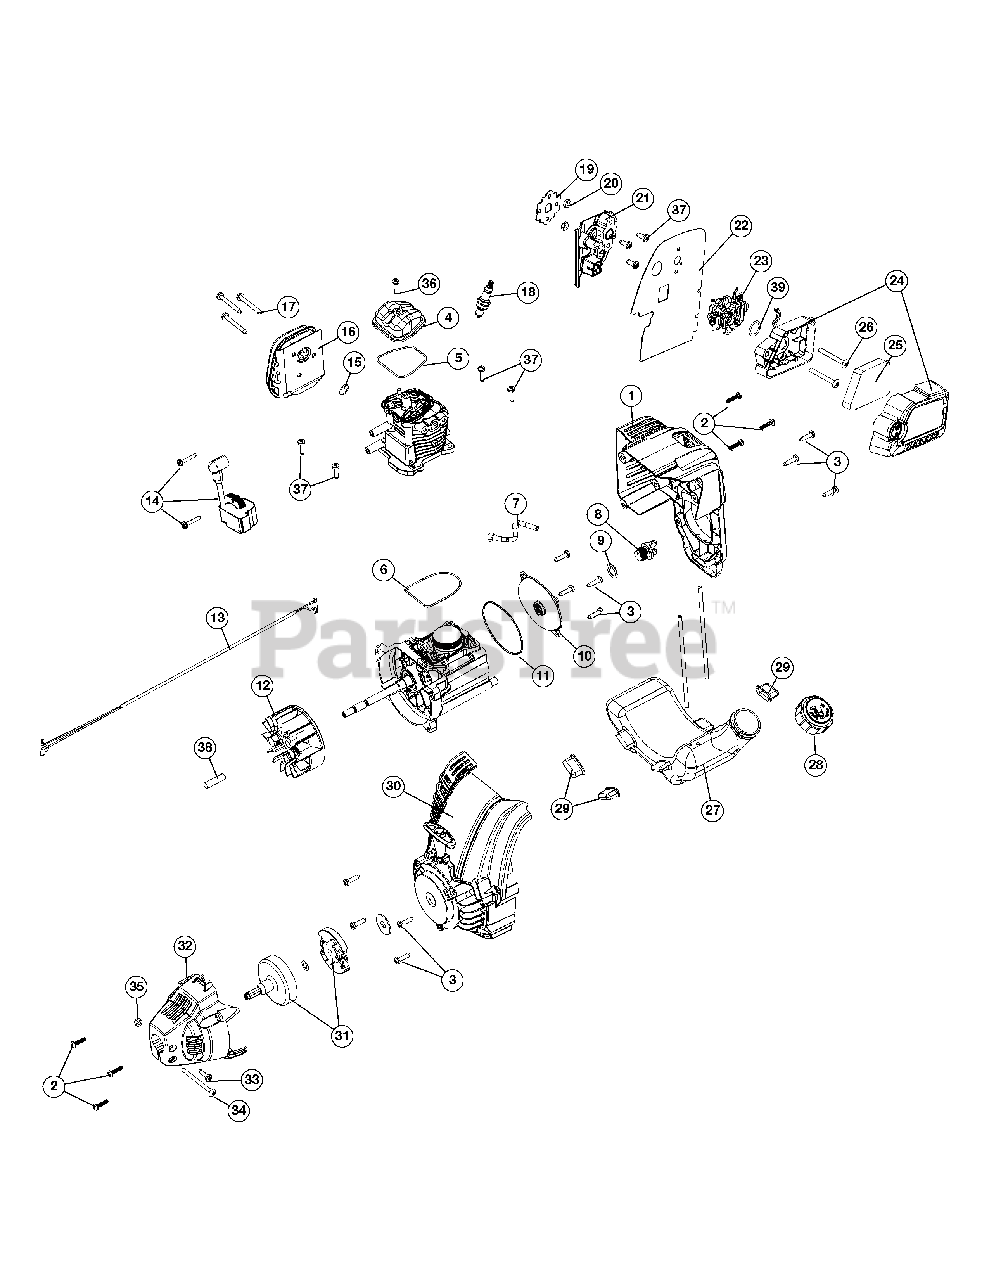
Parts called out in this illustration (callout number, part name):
1	Engine Cover Assembly
2	Cover Screw
3	Starter Screw
4	Rocker Cover
5	Rocker Cover O-Ring
6	Cylinder O-Ring
7	Breather Hose
8	Oil Plug
9	Oil Plug O-Ring
10	Crank Case Cover
11	Crank Case Cover O-Ring
12	Flywheel Assembly
13	Lead Wires
14	Module Assembly
15	Muffler Gasket
16	Muffler Assembly
17	Muffler Screw
18	Spark Plug
19	Insulator Gasket
20	Insulator Nut
22	Carburetor Gasket
23	Carburetor w/Primer
24	Air Cleaner Cover Assembly
25	Air Filter
26	Air Filter Screw
27	Fuel Tank Assembly w/Fuel Lines
29	Fuel Tank Pads
30	Starter Housing Assembly
31	Clutch Assembly
32	Clutch Cover
33	Anti-Rotation Screw
34	Clamp Screw
35	Clamp Nut
36	Rocker Cover Screw
37	Screw
